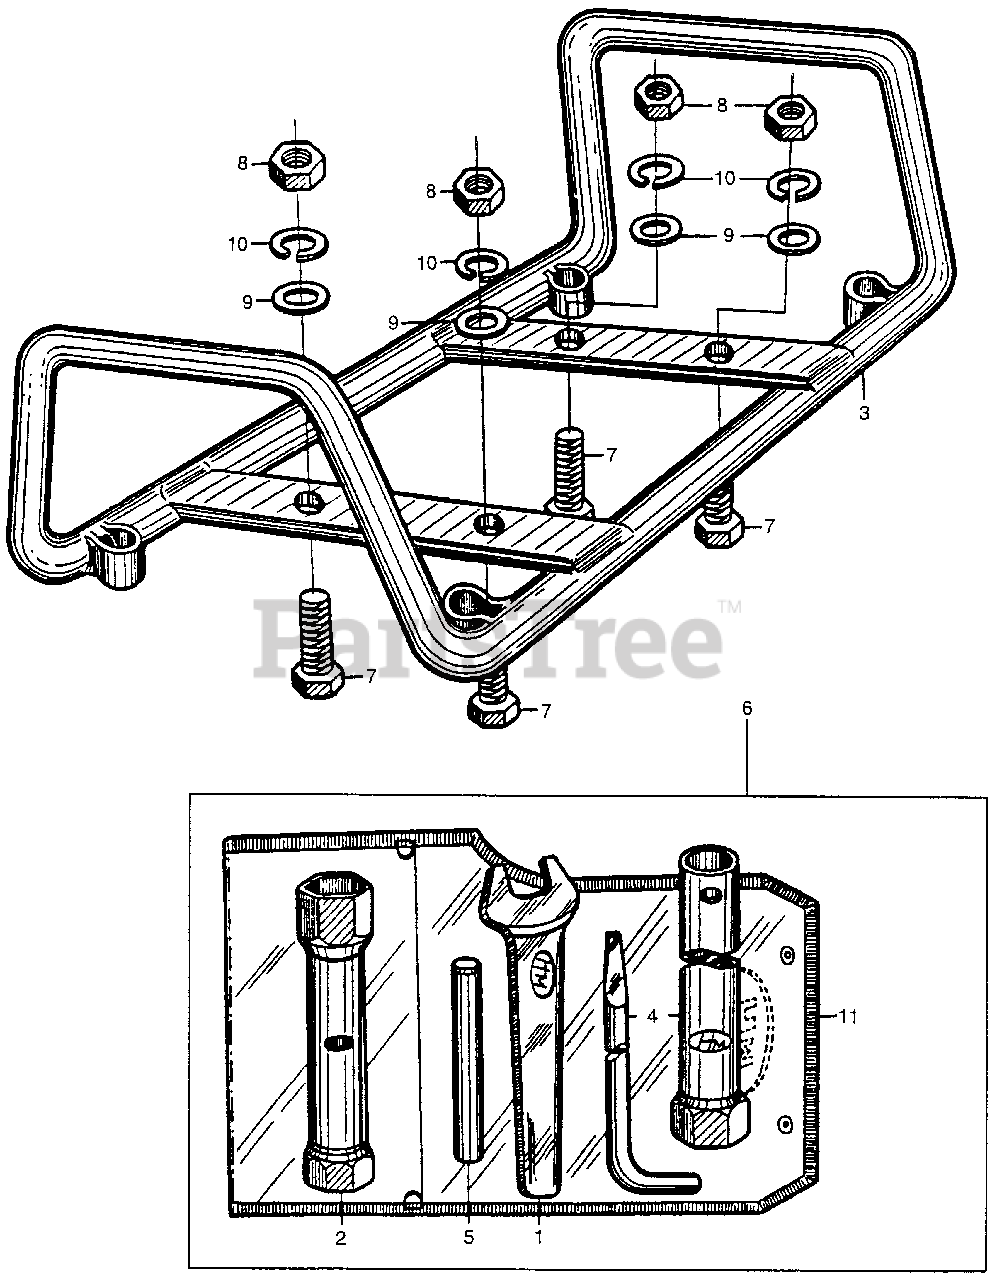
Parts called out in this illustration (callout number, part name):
1	WRENCH, OPEN END (7MM)
2	SPANNER (10X14)
3	BED, ENGINE *R2* (SCARLET)
4	WRENCH, SET PLUG
5	HANDLE, BOX WRENCH
6	TOOL SET (NOT AVAILABLE)
7	BOLT, HEX. (10X36)
8	NUT, HEX. (10MM)
9	WASHER, PLAIN (10MM)
10	WASHER, SPRING (10MM)
